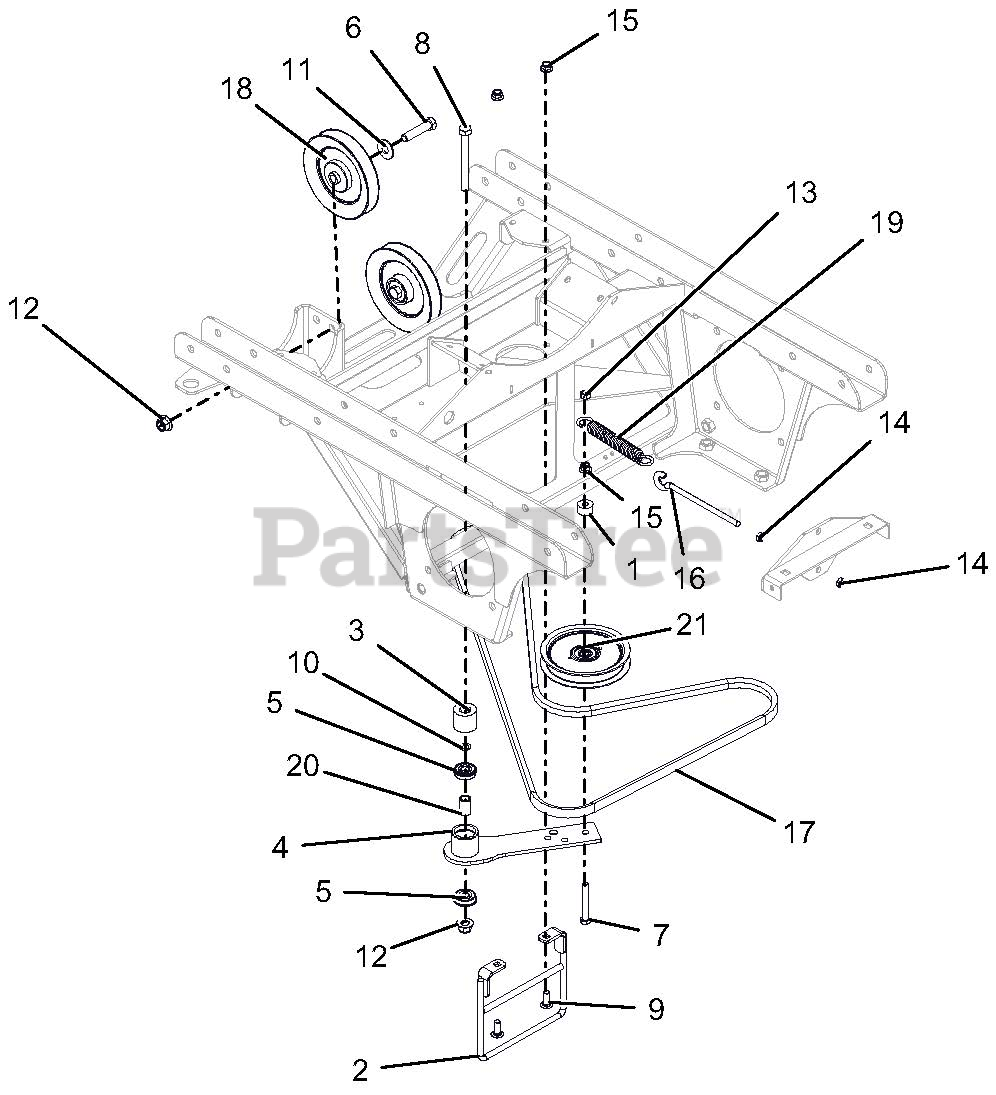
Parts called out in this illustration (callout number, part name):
1	SPACER .390X1.000X.562
2	WDMT, DIESEL BELT FINGER-BLK
3	SPACER, IDLER ARM MOUNT
4	HYDRO DRIVE IDLER ARM WMT- BLK
5	BRG-BALL .50X1.38X.438 SEALED
6	@BLT-HEX .50-13X2.25 GR5 YWZC
7	@BLT-HEX .38-16X2.75 GR5 YWZC
8	@BLT-HEX .50-13X4.50 GR5 YWZC
9	@BLT-RDHDSHSQNK.38-16X1.0 G5YZ
10	WASHER, .500X.750X.020 THRUST
11	@WSHR-FL-STL.563X1.38X.109YWZC
12	@NUT-LK-NYL-FLG .50-13 YWZC
13	@NUT-LK-CTR .38-16 YWZC
14	NUT-HEX-JAM .375-16 YWZC
15	@NUT-LK-NYL-FLG .38-16 YWZC
16	BOLT, .38-16X6.00 .62 DIA EYE
17	V-BELT, 5L-RAW EDGE
18	PLY-V 6.0 X .500 ID DBL BRG.
19	SPRING- EXTENSION
20	SPACER .510 X .867 X 1.1485
21	IDLER, FLAT-5.00X.75
